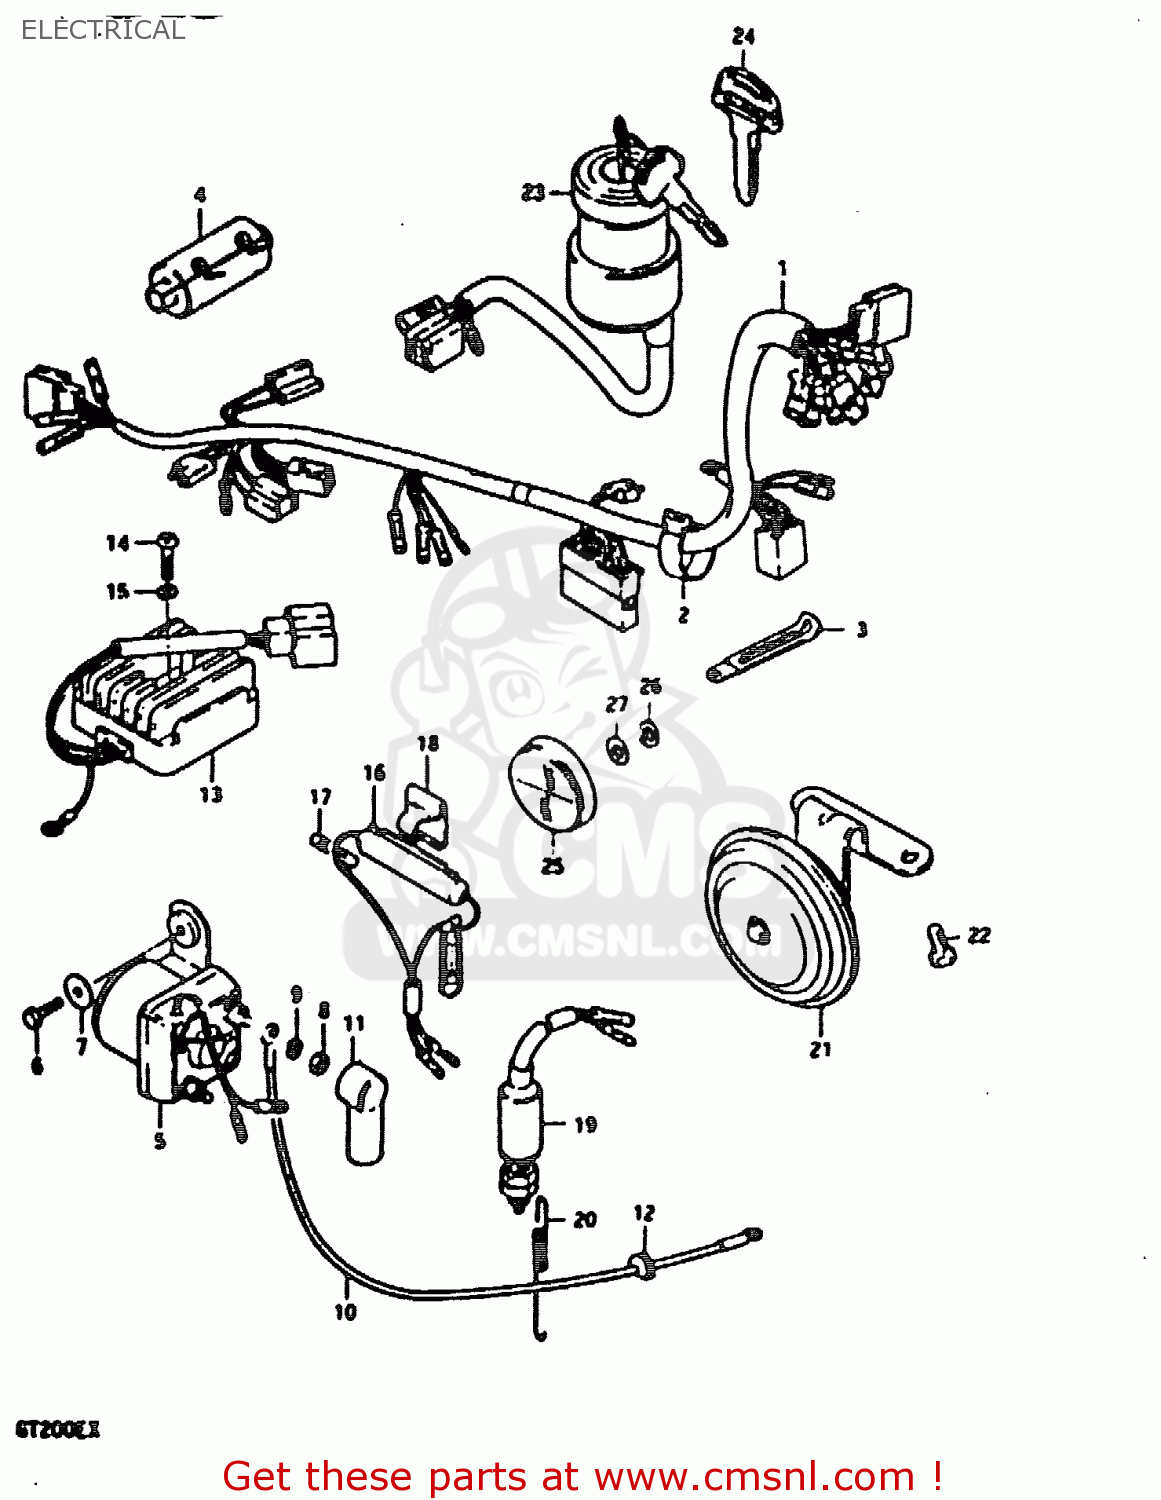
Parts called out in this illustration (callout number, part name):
1	WIRING HARNESS
2	CLAMP
3	CLAMP L:35
4	BOOT,WIRING HARNESS
5	RELAY,STARTER SWITCH
6	BOLT, UPPER
7	WASHER
8	NUT 6MM
9	LOCK WASHER
10	WIRE,STARTER MOTOR LEAD
11	CAP,STARTER RELAY
12	GROMET
13	RECTIFIER ASSY,REGULATOR
14	SCREW
15	LOCK WASHER
16	BOX ASSEMBLY,FUSE
17	FUSE(15A)
18	HOLDER,FUSE CASE
19	SWITCH,BRAKE LAMP
20	SPRING
21	HORN
22	BOLT
23	SWITCH ASSY, IGNITION
24	KEY,BLANK
25	REFLEX REFLECTOR,FR
26	LOCK WASHER
27	WASHER
